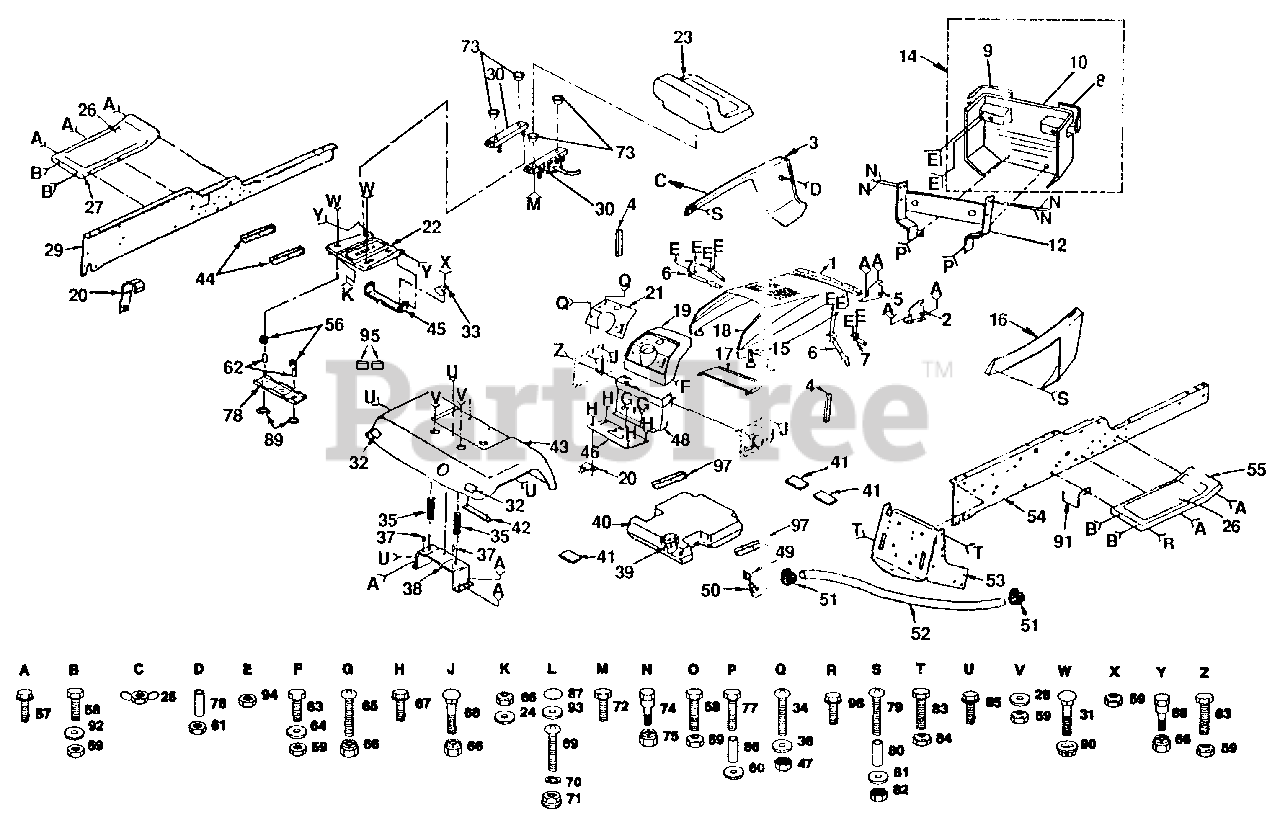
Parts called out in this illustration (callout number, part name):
1	Strip, Foam
2	Frame, Pivot, Ass'y, Bracket, R.H.
3	Panel, Side, L.H.
4	Strip, Foam
5	Frame, Pivot, Ass'y, Bracket, L.H.
6	Strap Assembly, Hinge, Rear
7	Strap Assembly, Hinge, Front
8	Lens, R.H.
9	Lens, L.H.
10	Grill
12	Support, Grill
14	Grill, Assembly
15	Latch, Hood
16	Panel, Side, R.H.
17	Support, Battery
18	Hood
19	Dashboard
20	Clip, Insulated
21	Dashplate
22	Pan, Seat
23	Seat
24	Washer 11/32 x 1 x 10 Gauge
25	Nut Wing 1/4-20
26	Pad, Footrest
27	Footrest, L.H.
28	Washer 13/32 x 1 x 14 Gauge
29	Rail, Frame, L.H.
30	Slide, Seat Set
31	Bolt, Carriage 1/4-20 x 1-3/8
32	Reflector, Taillight
33	Clip, Insulated
34	Screw, Mach. Hd. 5/16-18 x 3/4
35	Spring, Compression
36	Washer 11/32 x 11/16 x 16
37	Gauge Nut, Push
38	Bracket, Fender
39	Cap, Fuel
40	Tank, Fuel/sensor
41	Pad, Spacer
42	Strap, Fender
43	Fender
44	Foam, Strip
45	Bracket, Pivot, Seat
46	Cover, Shift, Gate
47	Nut, Keps 5/16-18
48	Dash Assembly
49	Bushing
50	Stem, Tank Fuel
51	Clamp, Hose
52	Fuel Line
53	Drawbar
54	Rail, Frame, R.H.
55	Footrest, R.H.
56	Spring, Compression
57	Screw, Hex Washer Thread Rolling 3/8-16 x 3/4
58	Bolt, Hex 3/8-16 x 3/4
59	Locknut 3/8-16
60	Washer 9/32 x 3/4 x 16 Ga.
61	Nut, Hex 1/4-20
62	Spacer, Split
63	Bolt, Hex 3/8-16 x 1
64	Washer 13/32 x 13/16 x 16 Gauge
65	Screw, Mach. Cr. Thrd. 5/16-18 x 3/4
66	Nut, Crownlock 5/16-18
67	Screw, Hex Washer Thrd. Cutting 1/4-20 x 1/2
68	Bolt, Carriage 5/16-18 x 3/4
69	Screw, Cr. Pan. Mach. #10 24 x 1/2
70	Washer, Lock #10
71	Nut, Weld
72	Screw, Hex 5/16-18 x 1
74	Bolt, Shoulder 1/4-20
75	Nut, Crownlock 1/4-20
77	Bolt, Fin Hex 1/4-20 x 2-1/2
78	Bracket, Switch Mount
79	Screw, Mach Cr. Pan #10-24 x 1-1/4
80	Spacer, Split #10 x 3/4
81	Washer 7/32 x 1/2 x 18
82	Gauge Nut, Keps #10-24
83	Bolt, Hex 7/16-14 x 1
84	Locknut 7/16-14
85	Screw, Hex Washer Thread Rolling 3/8 x 16 x 1/2
88	Bolt, Shoulder
89	Bushing, Snap
90	Nut, Flange Lock 1/4-20
91	Retainer, Belt, Lower
92	Washer 13/32 x 13/16 x 17
93	Gauge Washer, Snap Cap
94	Nut, Hex 1/4-20
95	Cap, Spring
96	Screw, Hex, Washer Thrdrol 3/8-16 x 1
97	Pad, Idler
